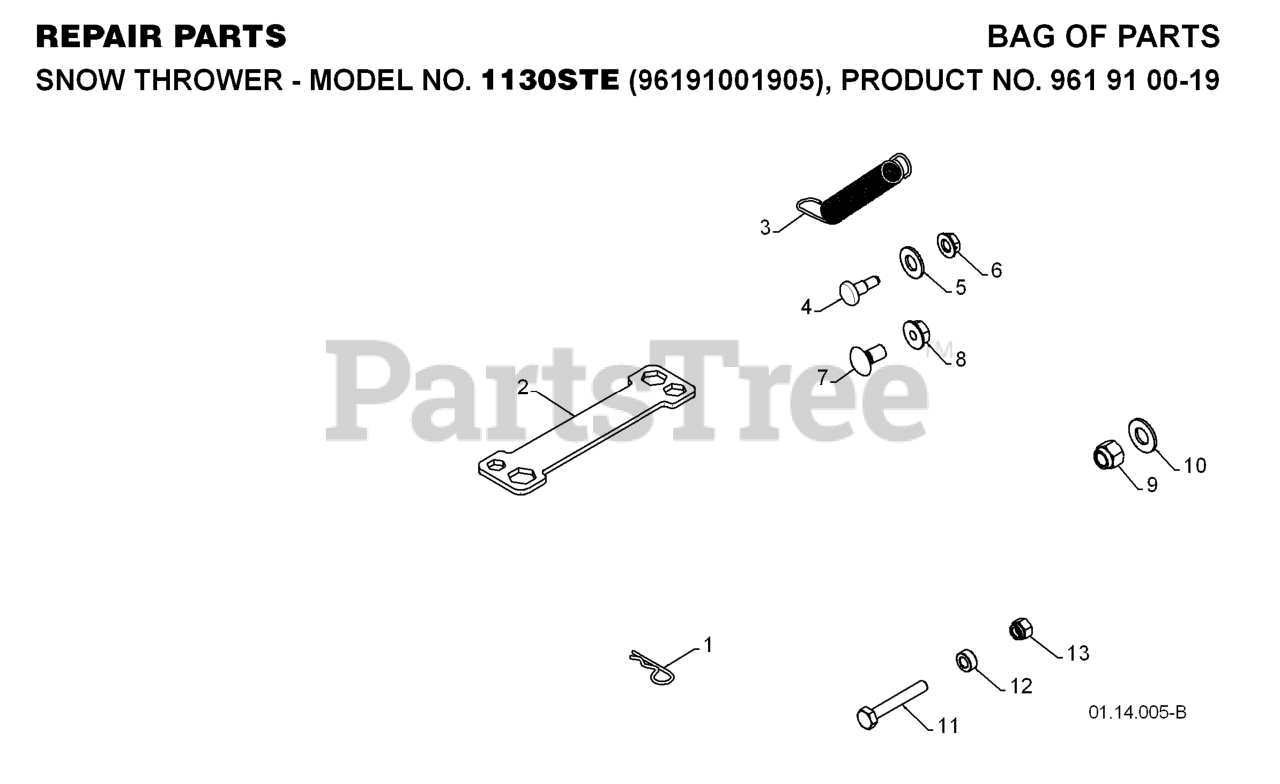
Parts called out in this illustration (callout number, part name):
1	SPRING RETAINER
2	RP WRENCH, SNOWTHROWER
3	SPRING.DEFLECTOR.REM.CHUTE
4	BOLT, SHOULDER
5	WASHER, NYLON FRICTION
6	NUT.HEX.FLANGE.1/4
7	BOLT
8	NUT.LOCK.5/16-18
9	NUT
10	WASHER
11	BOLT, SHEAR
12	SPACER.3943.SLEEVE.250X.47
13	LOCKNUT.NYLOC.1/4-20
